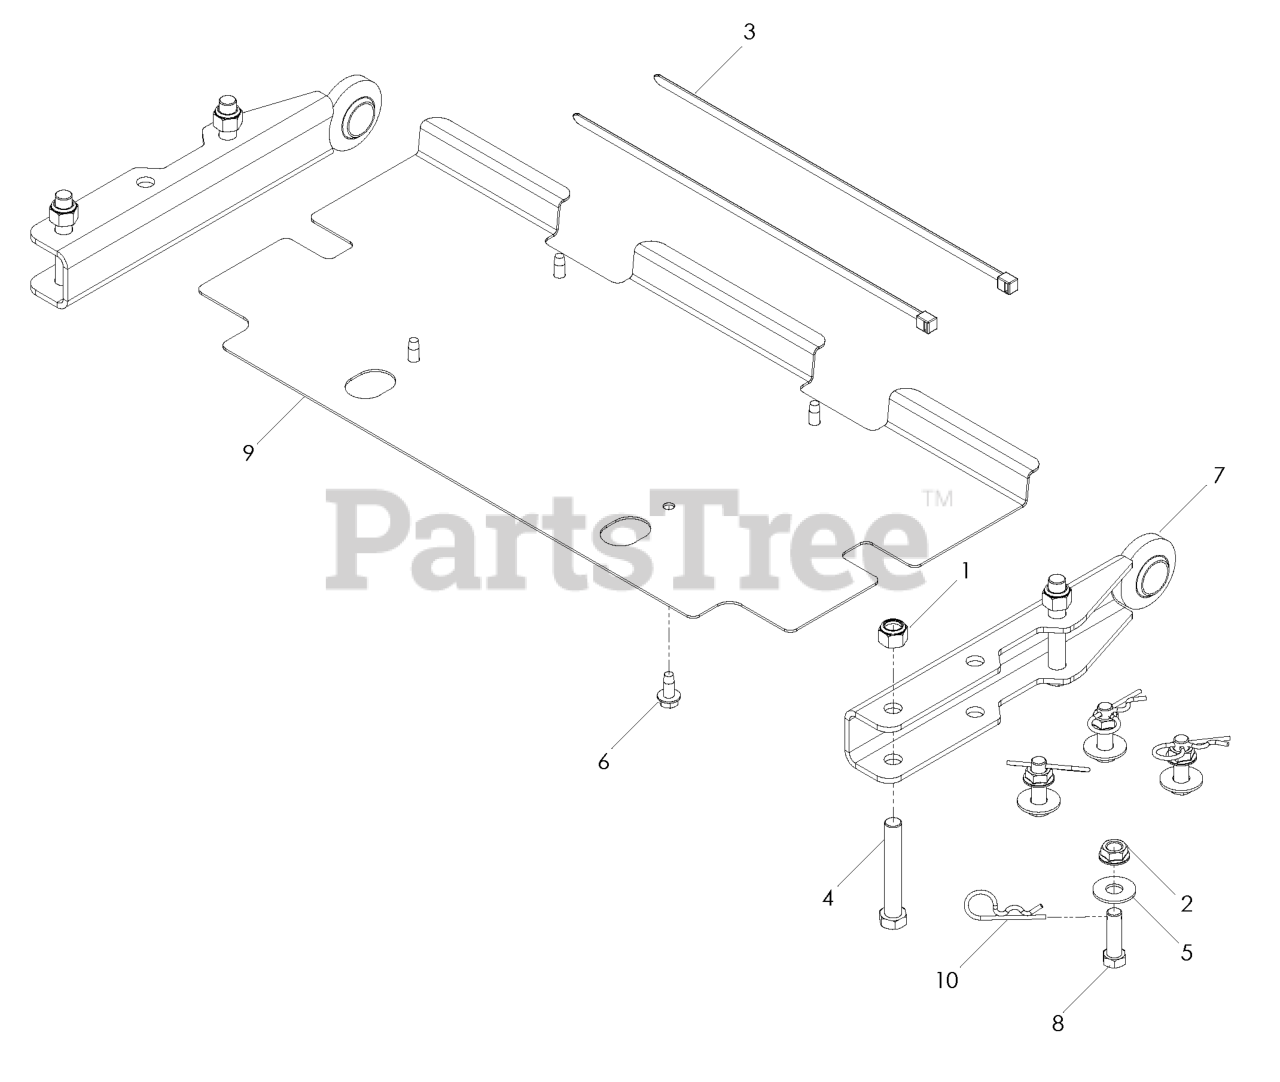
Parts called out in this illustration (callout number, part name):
1	Nut 1/2-13 Hex Nyloc
2	Nut 7/16-14, Whizlk
3	Plastic Tie
4	Hcs 1/2-13 x 3 1/4
5	Washer 7/16
6	Bolt 5/16-18 x 3/4 Trd Frm
7	Strut, Rear
8	Hcs 7/16-14 x 1 1/2, Spec
9	Rear Debris Shield
10	Hairpin #4
